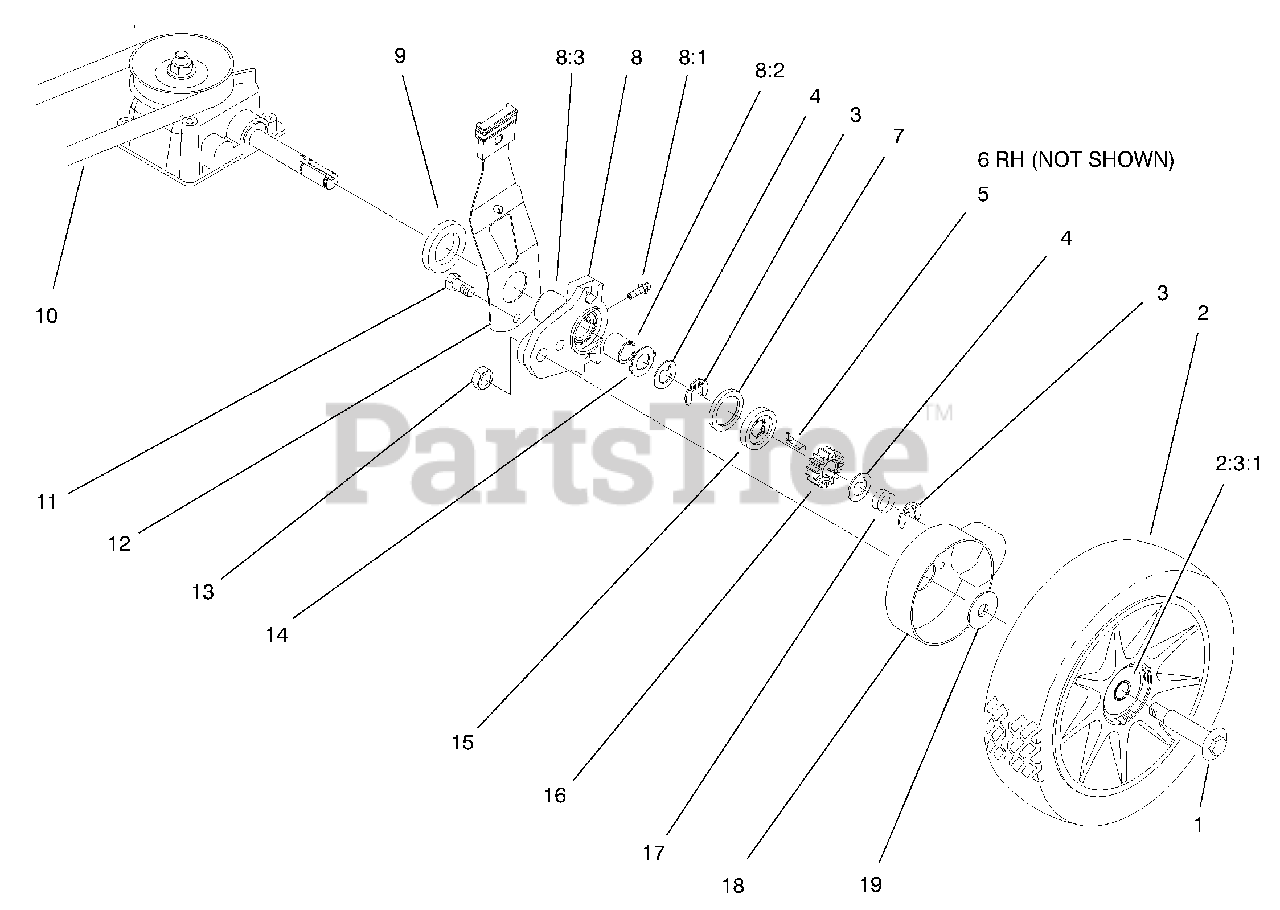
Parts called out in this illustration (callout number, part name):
1	Shoulder Bolt
2	8" Wheel & Tire ASM.
2:3	8" Wheel & Tire ASM
3	Klip Ring-Special
4	Washer-Keyed Thrust
5	Key-Rocking LH
6	Key-Rocking
7	Ring-Friction
8	ASM-Hgt Adj Arm, Rear
8:1	Fitting-Zerk
9	Spacer-Axle Shaft
11	Screw-TAP
12	Spring Arm ASM-Rear
13	Nut-Jam, Locking
14	Washer-Pivot Arm
16	Pinion-Gear, 15T
17	Spring-Compression
18	Cover-Wheel
19	Washer-Stepped
